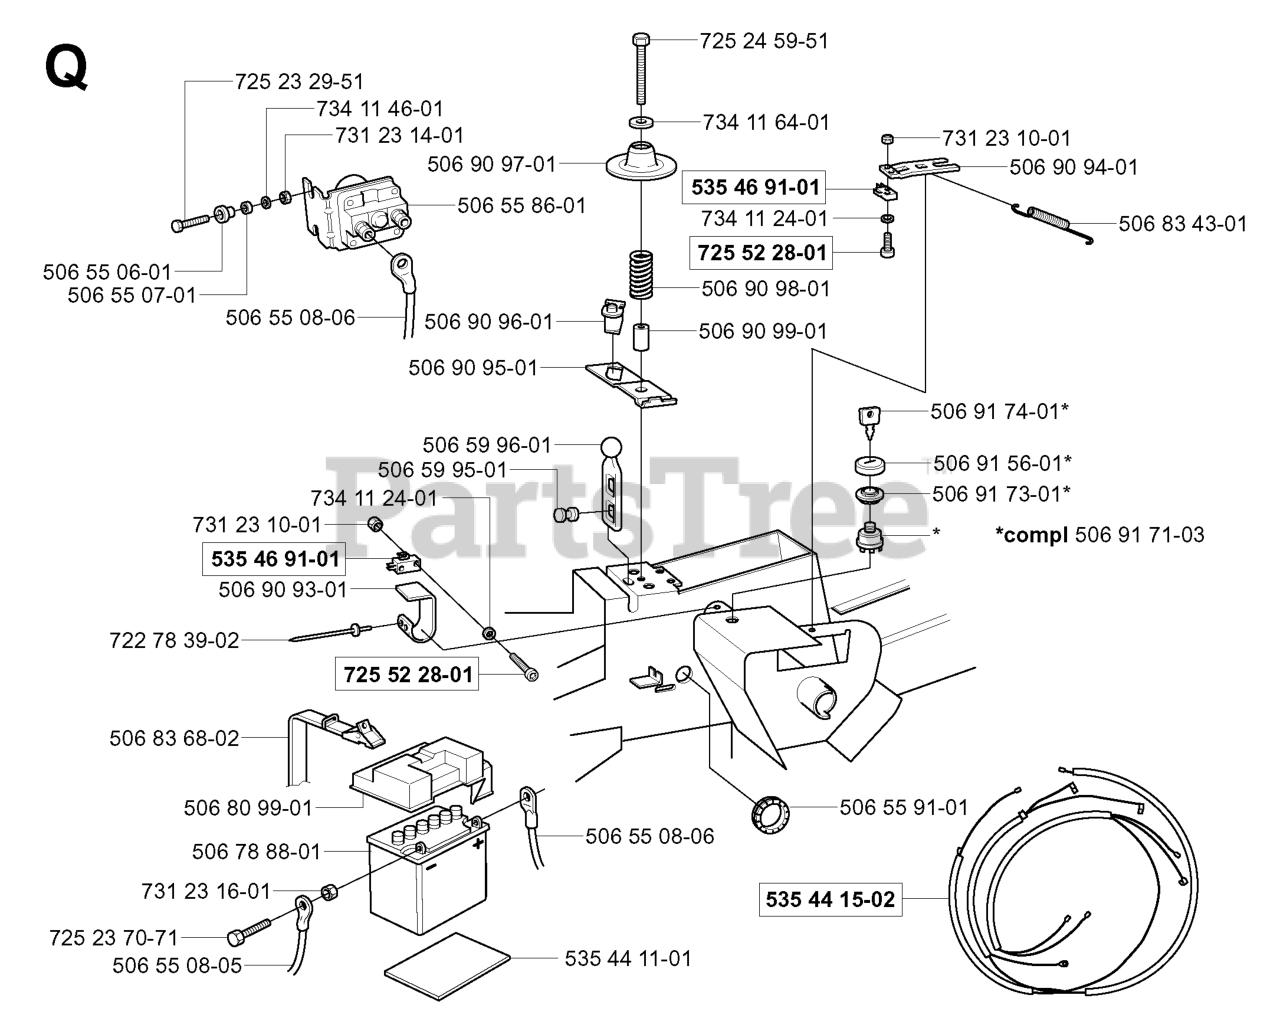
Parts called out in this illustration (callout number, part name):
860	ROD, MID CHUTE CTL
861	ROD, ASSY CHUTE LWR
863	PIN, COTTER .090/.086X.75
931	ROD CHUTE CTRL UPR, ASSN
932	SCREW, 10-32 X .88 SLTRHD
933	NUT, #10-32 CTRLK
934	KNOB, CHUTE CRANK
935	NUT, PUSH, FTS 3/8 DIA
